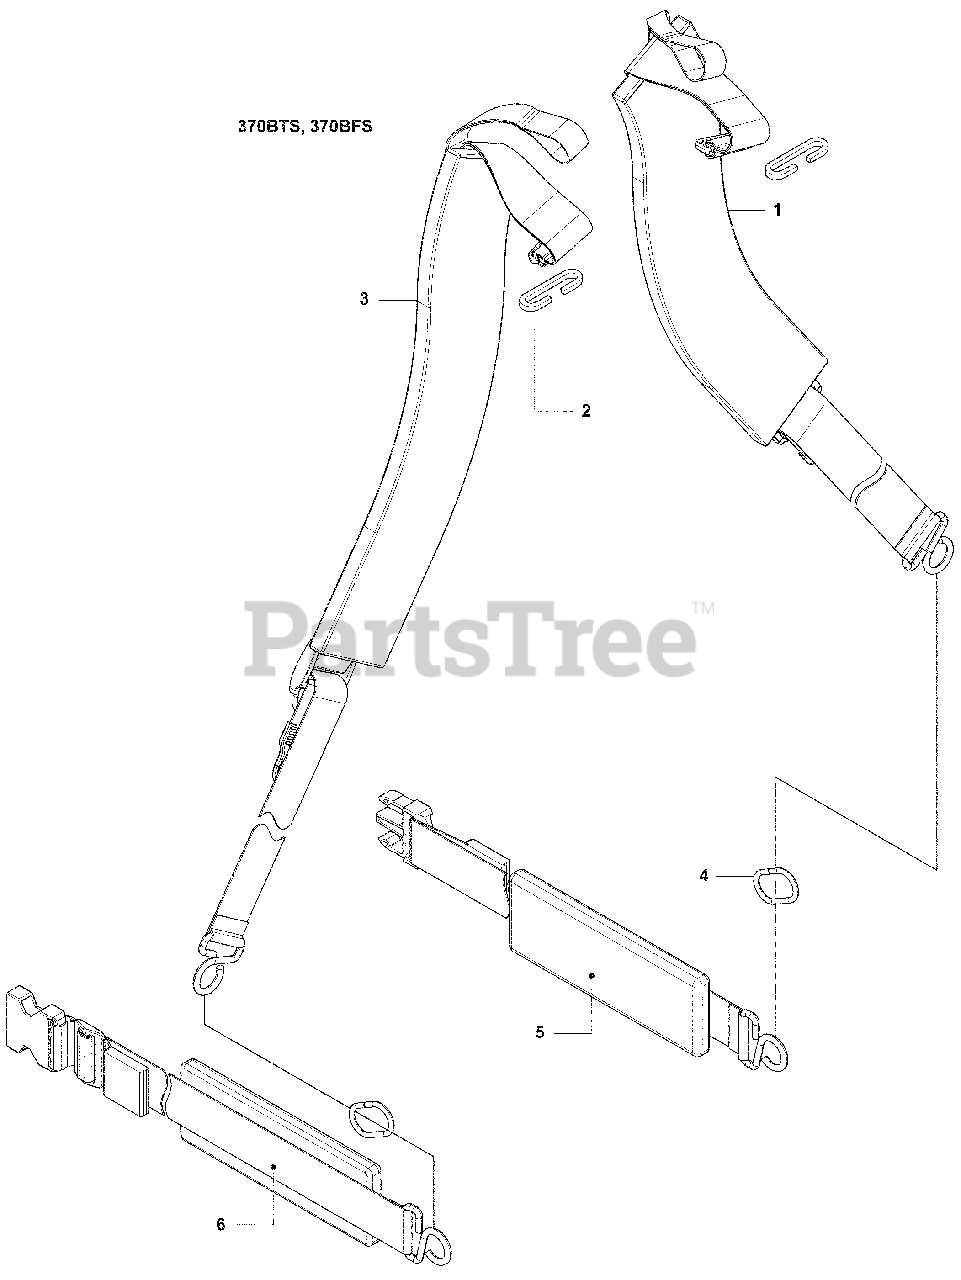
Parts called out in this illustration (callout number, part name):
1	Shoulder Strap, RH
3	Shoulder Strap, LH
4	Ring
5	Shoulder Strap, RH
6	Shoulder Strap, LH
